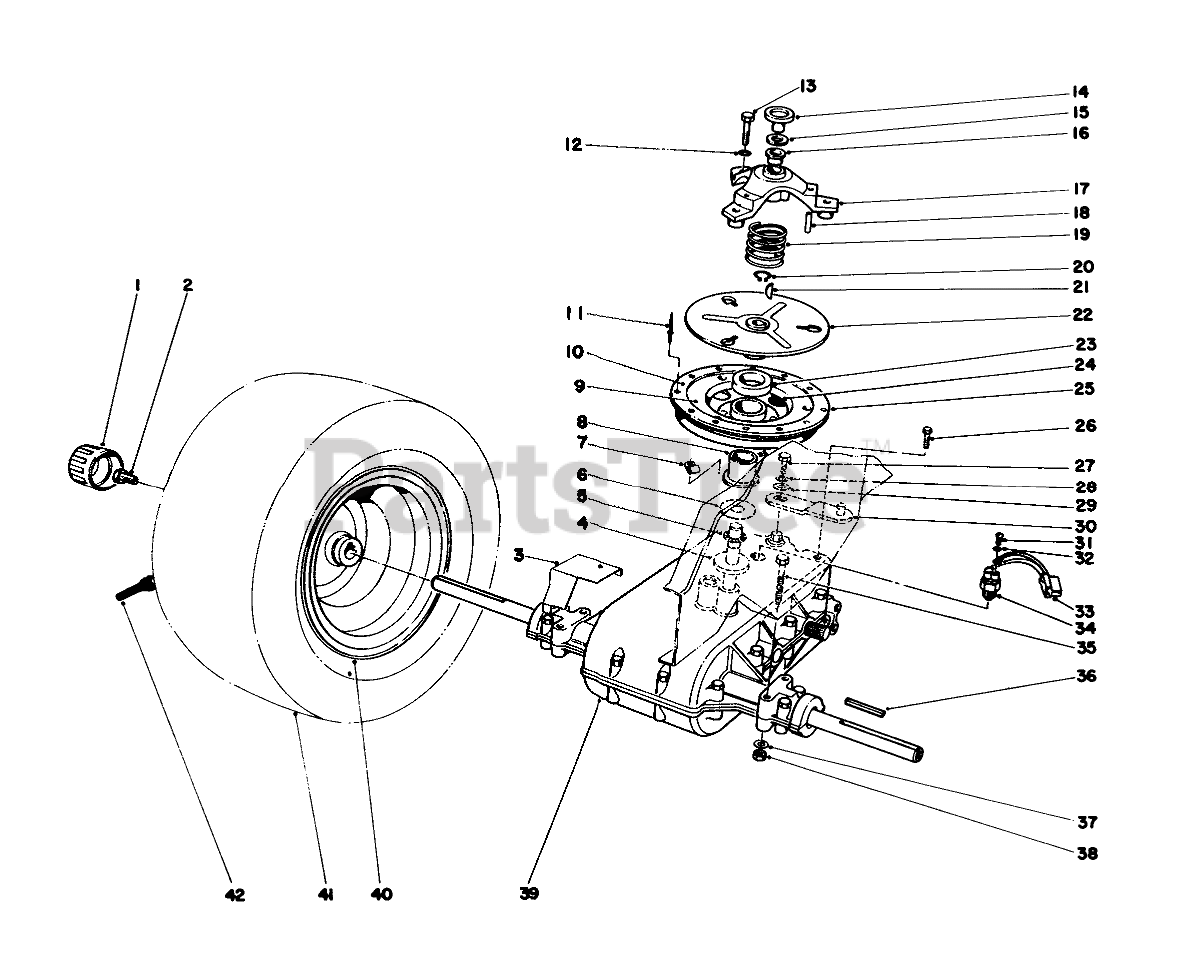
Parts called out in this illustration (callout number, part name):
1	CAP-HUB
2	CAPSCREW 3/8 16 3/4
3	GRASS SHIELD B
4	SPACER
5	NEEDLE BRG
6	THRUST WASHER
7	Clamp (Incl. with Main Wire Harness)
9	CLUTCH PAD
10	RETAINER RING R
11	RIVET
12	WASHER-LOCK
13	SCREW-HH
14	CLUTCH CAP
15	THRUST RACE
16	BUSHING-FLANGE
17	Clutch Cover Assembly (Incl. Ref. #16 & 18)
18	NEEDLE BRG
19	COMPRESSION SPRING
20	9/16X039 IN SNAP RING
21	KEY-WOODRUFF
22	Clutch Plate
23	WASHER FELT
25	Sheave Assembly (Incl. Ref. #8-11)
26	SCREW-HWHTF
27	SCREW-HH
28	WASHER-LOCK
29	WASHER-FLAT
30	SHIFT LEVER WA B
31	SCREW
32	WASHER-LOCK/INT
33	WIRE HARNESS
34	NEUTRAL SWITCH
35	SCREW-HH
37	WASHER-PLAIN
38	NUT-LOCK, NI
39	TRANSAXLE
40	REAR WHEEL ASSEMBLY
41	REAR TIRE
42	STEM-VALVE
